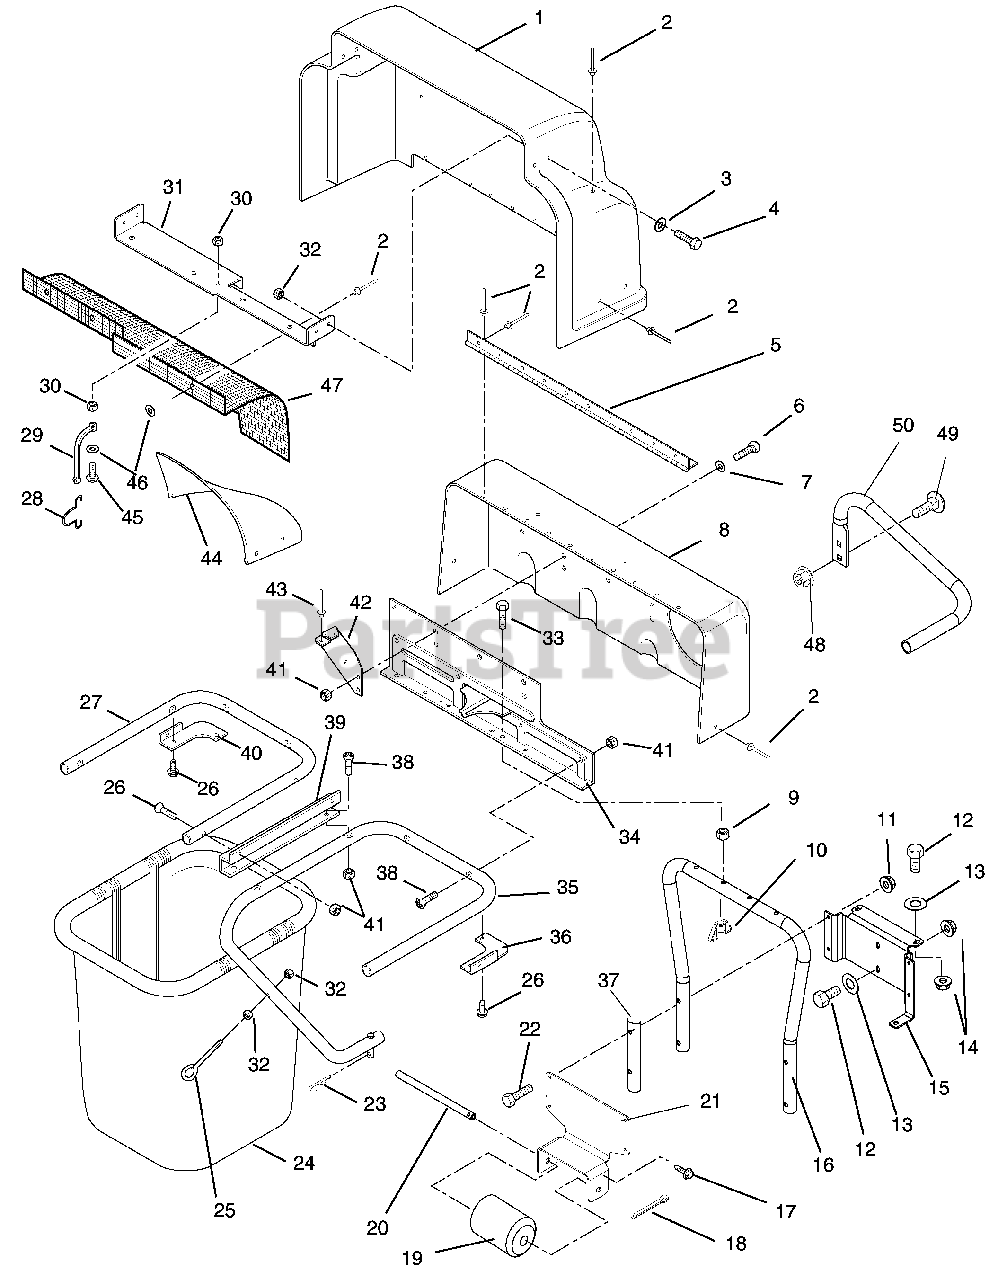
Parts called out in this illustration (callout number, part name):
1	HINGED COVER W/DECALS
2	RVT-POP .187X.402 DOME ST
3	@WSHR-FL-STL.281X.62X.065 YWZC
4	@BLT-HEX .25-20X.50 GR5 YWZC
6	@BLT-HEX .31-18X.75 GR5 YWZC
7	WSHR-FL-STL .328X.875X.062YWZC
8	STATIONARY COVER
9	@NUT-HEX .31-18 YWZC
10	NUT-NYLK WING .312-18 YWZC
11	@NUT-LK-TOP-FLG .31-18 YWZC
12	@BLT-HEX .38-16X1.00 GR5 YWZC
13	@WSHR-FL-STL.38X.875X.083 YWZC
14	@NUT-LK-TOP-FLG .38-16 YWZC
15	ASSY,MOUNT BRACKET
17	@SCR-TAP .25-20X.50 HWH TR YWZ
18	@PIN-CTR .25X2.00 YWZC
21	BRACKET, ROLLER
22	@BLT-HEX .31-18X1.50 GR5 YWZC
23	PIN-HAIR INT .08X.38X1.42 YWZC
24	GRASS BAGGER BASKET
25	EYEBOLT
26	@SCR-TAP .31-18X.50 HWH TR YWZ
27	CENTER TUBE
29	BATTERY STRAP
30	@NUT-LK-NYL 10-24 W/INSRT YWZC
31	COVER BRACKET
32	@NUT-LK-CTR .25-20 YWZC
33	BLT-HEX .31-18X1.75 FLTHD YWZC
34	MOUNTING BRACKET
35	RIGHT TUBE
36	RH CORNER BRACKET
37	BRACE
38	SCR-MCH .31-18 X 1.50 YWZC
39	TUBE BRACKET
40	LH CORNER BRACKET
41	@NUT-LK-CTR .31-18 YWZC
43	RVT-POP.187X.527 DOME ST
45	SCR-MCH 10-24X.88 SLRH YWZC
46	@WSHR-FL-STL.219X.50X.049 YWZC
47	SCREEN, BAGGER
48	@NUT-SPNLK-FLG .375-16 YWZC
49	@BLT-RDHDSQNK .38-16X.75 G5YZ
50	SUPPORT, 28" BAGGER TUBE
